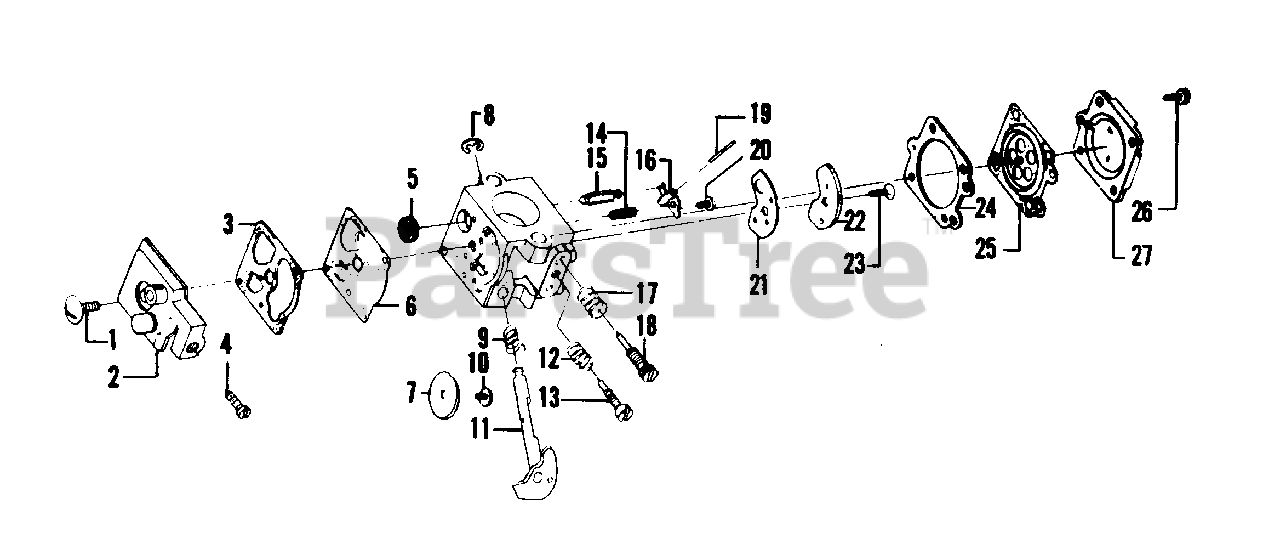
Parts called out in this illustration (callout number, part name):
1	Screw - Pump Cover
2	Pump Cover Ass'y (Inc. #4)
3	Gasket - Pump
4	Screw - Idle Adjustment
5	Screen - Inlet
6	Diaphragm - Pump
7	Valve - Throttle
8	Clip - Throttle Shaft
9	Spring - Throttle Return
10	Screw - Throttle Valve
11	Shaft Assembly - Throttle
12	Spring - Idle Needle
13	Needle - Idle
14	Spring - Metering Lever
15	Valve - Inlet Needle
16	Lever - Metering
17	Spring - Hi Speed Needle
18	Needle - Hi Speed
19	Pin - Metering Lever
20	Screw - Metering Lever Pin
21	Gasket - Circuit Plate
22	Plate - Circuit
23	Screw - Circuit Plate
24	Gasket - Metering Diaphragm
25	Diaphragm Assembly - Metering
26	Screw Assembly - Metering Cover & Throttle Shaft Clip
27	Cover - Metering Diaphragm
